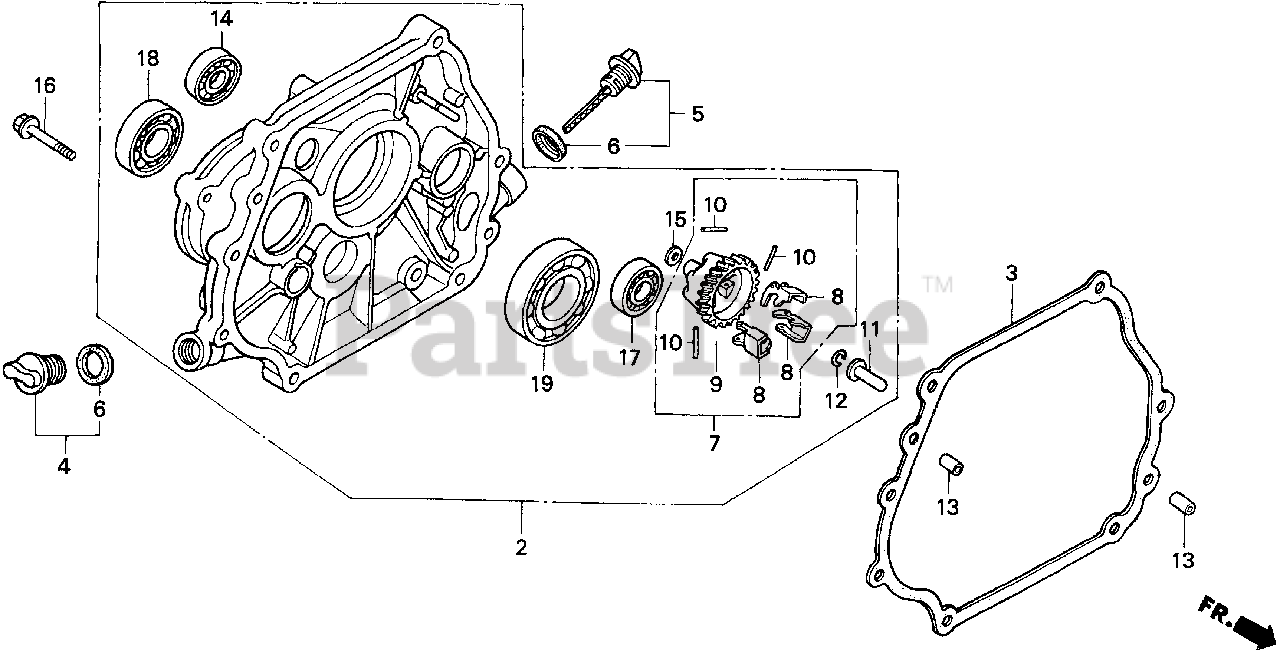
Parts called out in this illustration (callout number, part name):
2	COVER ASSY., CRANKCASE (L-TYPE)
3	GASKET, CASE COVER
4	CAP ASSY., OIL FILLER
5	CAP ASSY., OIL FILLER
6	GASKET, OIL FILLER CAP
7	GOVERNOR ASSY.
8	WEIGHT, GOVERNOR
9	HOLDER, GOVERNOR WEIGHT
10	PIN, GOVERNOR WEIGHT
11	SLIDER, GOVERNOR
12	CLIP, GOVERNOR HOLDER
13	PIN, DOWEL (8X12)
14	BEARING, RADIAL BALL (6202)
15	WASHER, PLAIN (6MM)
16	BOLT, FLANGE (8X40)
17	BEARING, RADIAL BALL (6202)
18	BEARING, RADIAL BALL (6204)
19	BEARING, RADIAL BALL (6207)
